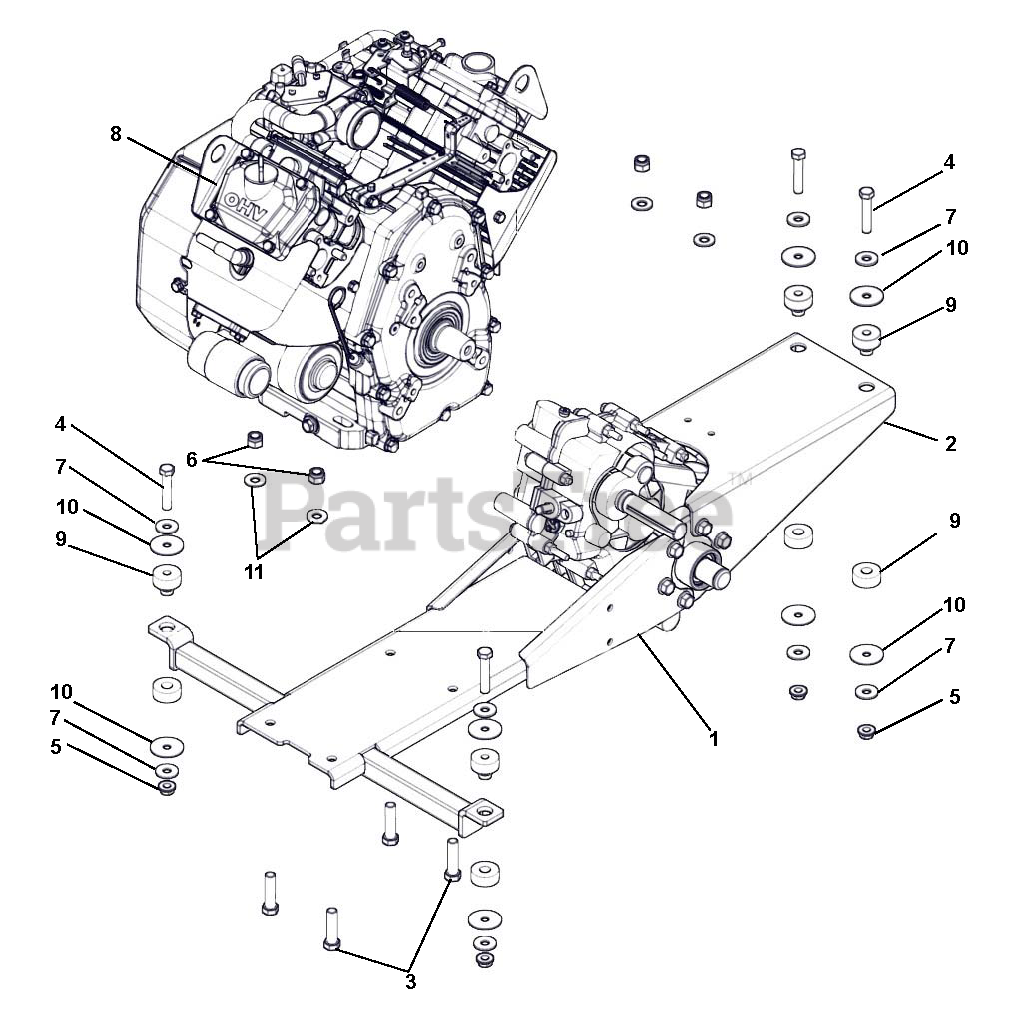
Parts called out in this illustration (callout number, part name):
1	ENGINE MOUNT WELDMENT
2	TRANS MNT SUPPORT BRACKET ST
3	@BLT-HEX .44-14X1.75 GR5 YWZC
4	@BLT-HEX .38-16X2.00 GR5 YWZC
5	@NUT-LK-TOP-FLG .38-16 YWZC
6	NUT-LK-TOP .437-14 GR C PL
7	@WSHR-FL-STL.438X1.00X.083 YWZ
8	ENGINE, SUBARU EH65
9	MOUNT MOTOR H SYTLE
10	WSHR-FL-STL .402X2.00X.055 YWZ
11	@WSHR-FL-STL.531X1.06X.095YWZC
